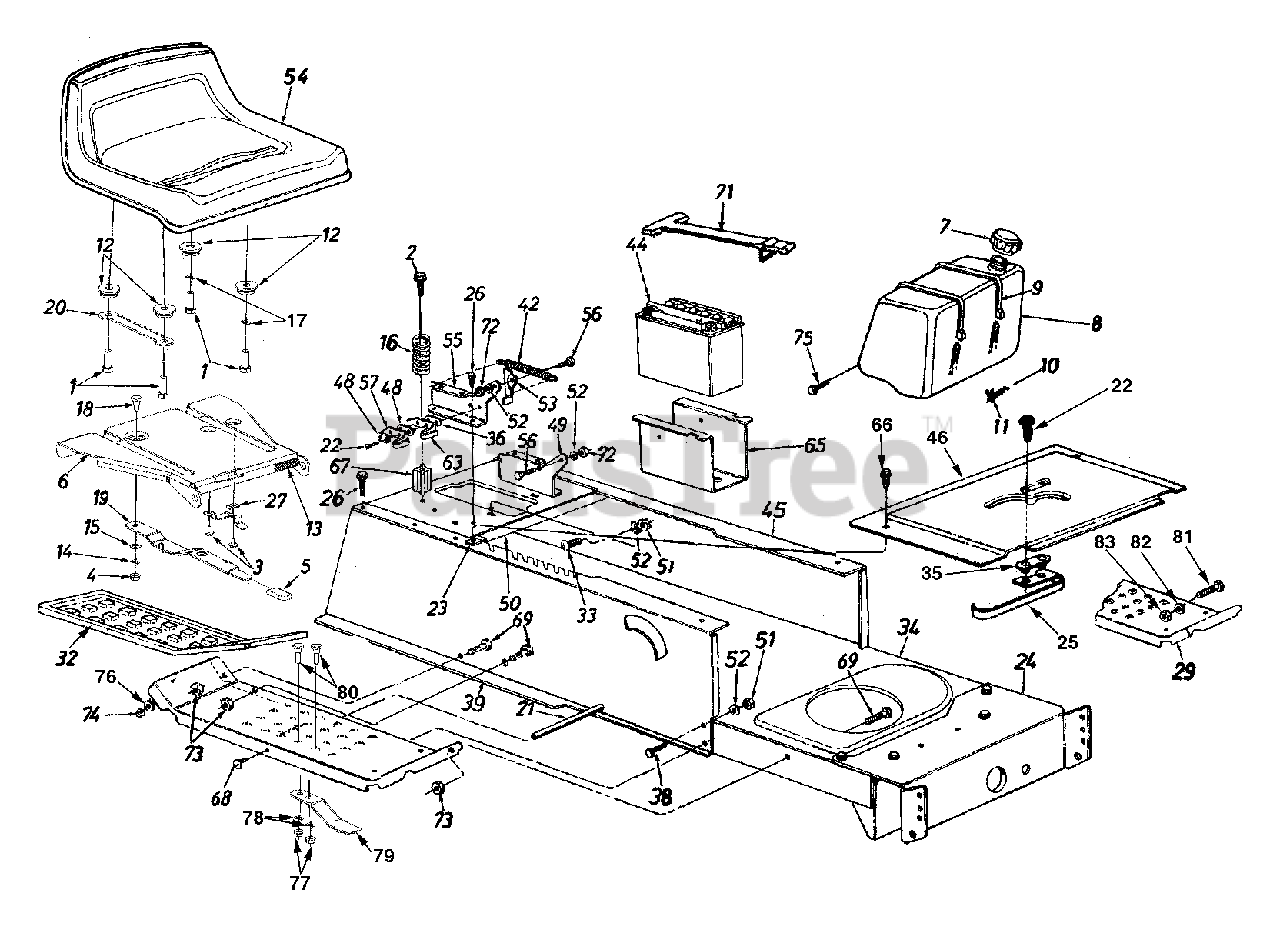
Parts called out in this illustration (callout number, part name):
1	Shoulder Screw 3/8-16 x .5
2	Hex Washer Tap Scr. 5/16-18 x 3.25"
3	Hx Scr. B-Tap Wash. #10-16:.38
4	Lock Nut 1/4-20
8	Fuel Tank
9	Tie Strap
10	Fuel Line
13	Compression Spring
14	Wash. Spring .265 x .562 x .025
15	Fl. Wash. .344 ID x .62 OD x .03
16	Compression Spring
17	Flat Washer .535 x .93 x .090
18	Shldr. Scr. .340 x .285 - 1/4-20
20	Seat Selector
21	Running Board Rod
22	Hex AB-Tap Scr. #8 x .50"
23	Speed Nut #10Z
25	Reverse Safety Switch
26	Hex Washer AB-Tap Scr. 5/16 x .75"
33	Truss Mach. Scr. 5/16-18 x .75" Lg.
35	Insalatop Nut Plate
36	Insulator Boss Plate
38	Hex Bolt 5/16-18 x .75" Lg.
44	12-V Battery
48	Insulator Plate
52	L-Wash. 5/16" I.D.
53	Seat Lift Brkt.
54	Seat
56	Shld. Bolt .437" Dia. x .268"
57	Spring Switch
63	Safety Switch (Seat)
66	Truss Mach. B-Tap Scr. #10 x .5"
67	Spring Spacer
68	Pan Hd. Scr. 5/16-18 x .75"
69	Hex Bolt 5/16-18 x .75"
71	Battery Retainer Strap
72	Hex Nut 5/16-18 Thd. (Gr. 5)
73	Hex Sems Nut 5/16-18 Thd.
74	Hex Sems Nut 1/4-20 Thd.
75	Hex Screw 12-24 x .62
76	Bell Wash. .265 x .75 x .062
77	Hex Nut 1/4-20 Gr. 5
78	L-Wash.
79	Blade Brake Asm.
80	Hex Carriage Screw 1/4-20 x .75"
82	Spring Wash.
83	Hex Nut 3/8-16 Gr. 5
